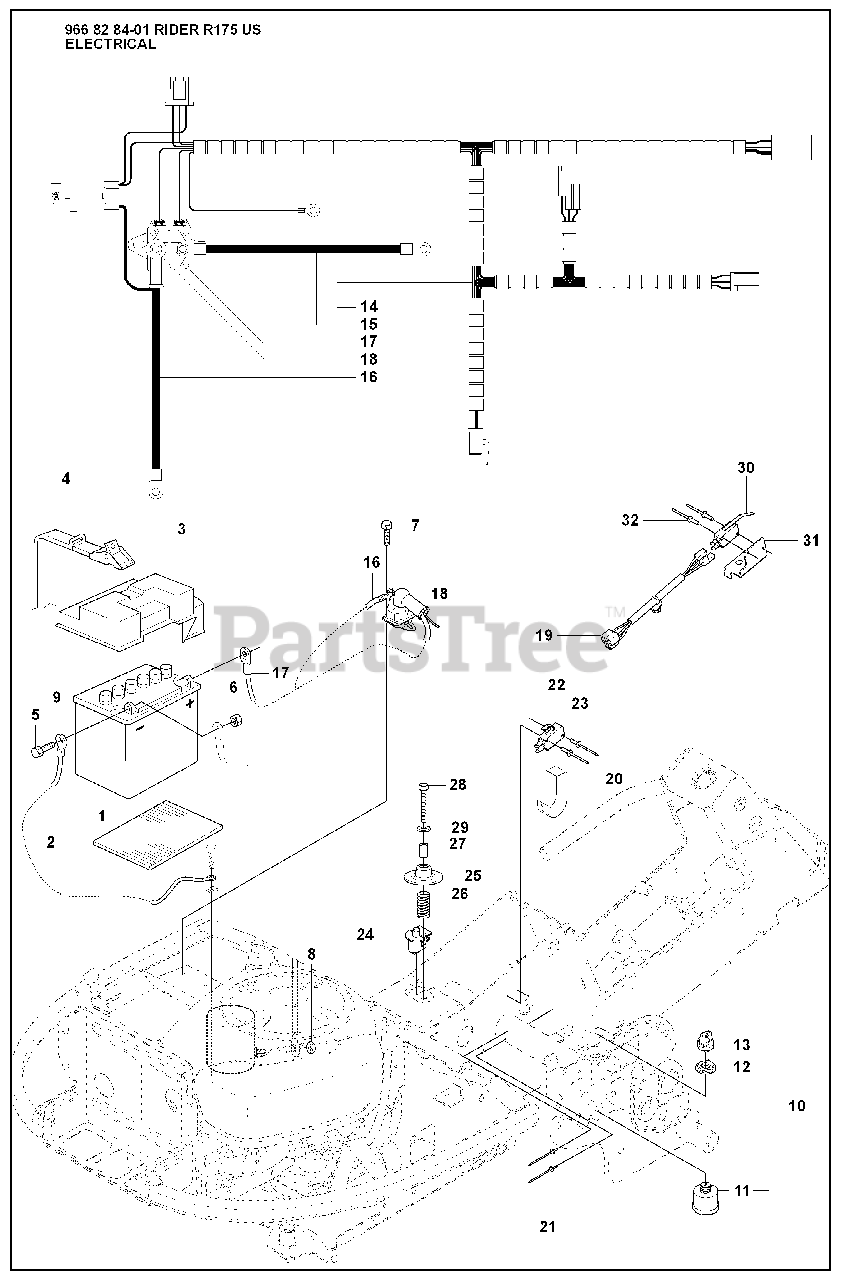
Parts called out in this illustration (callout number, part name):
1	BATTERY - DRY
10	IGNITION SWITCH
11	IGNITION SWITCH
13	IGNITION KEY
19	WIRING
22	%BRAKER
27	SPACER TUBE
28	SCREW
29	WASHER BRB 8.4X17
30	RP MICRO SWITCH
